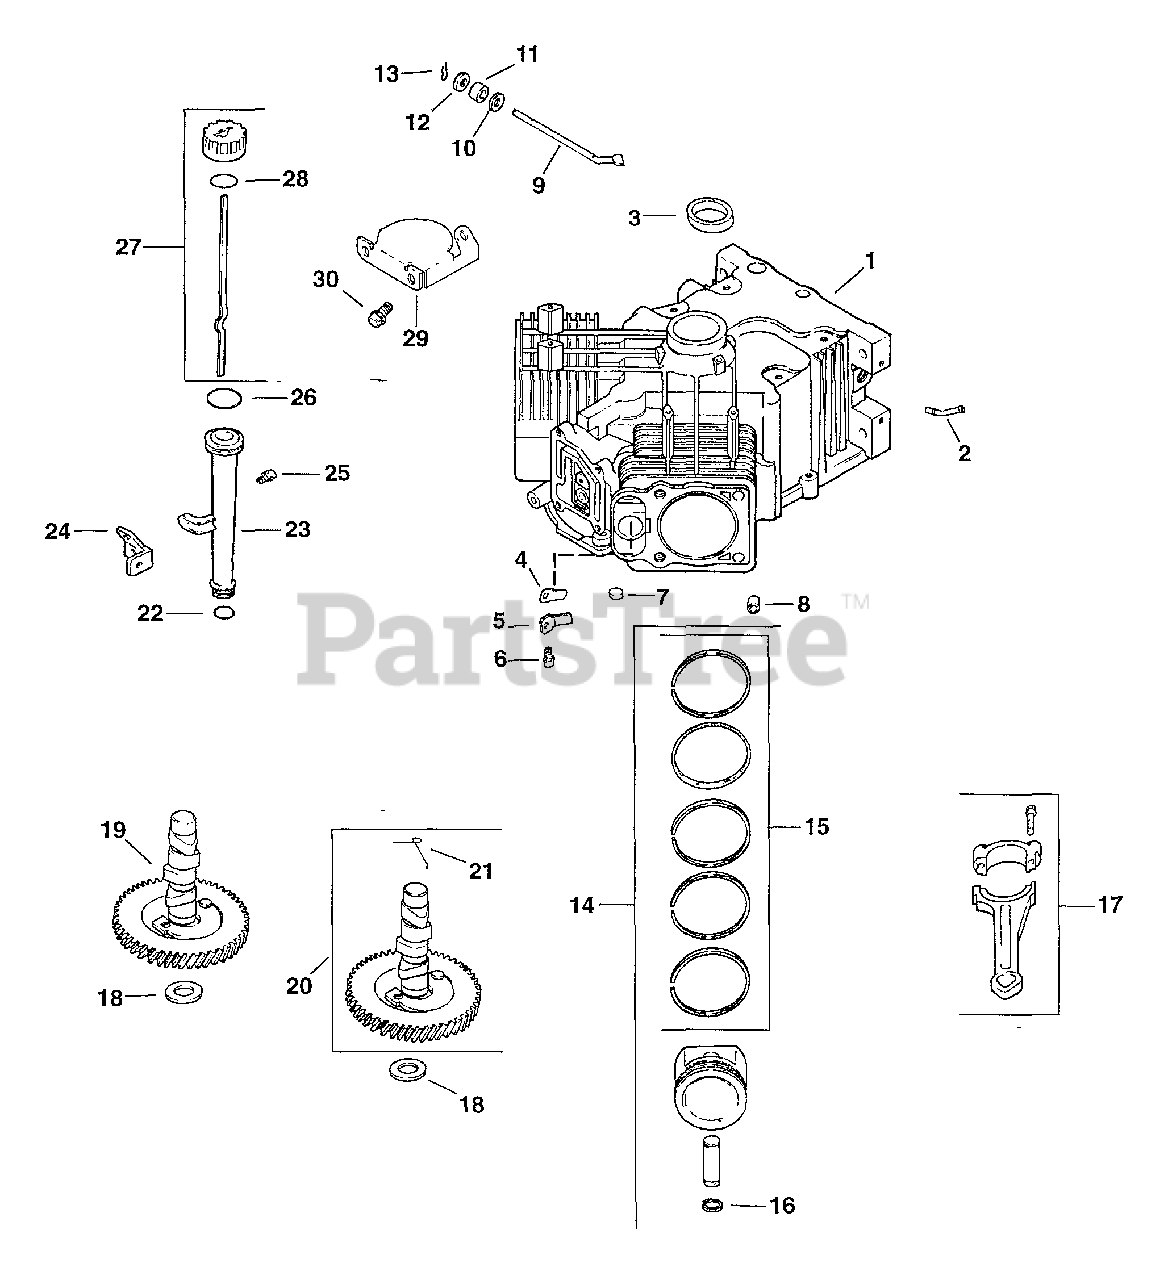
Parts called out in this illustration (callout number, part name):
2	FITTING - USE 24 294 13
3	SEAL, OIL FRONT-USE 24 032 19-S
4	REED, BREATHER
5	RETAINER, BREATHER REED
6	SCREW - USE M-545010
7	PLUG, CUP
8	PIN - USE 12 380 17
9	SHAFT, GOVERNOR CROSS - (#DSC)
10	WASHER, FLAT 1/4"
11	SEAL, GOVERNOR CROSS SHAFT
12	WASHER, FLAT 1/4" (O.D. 1/2")
14	PISTON W/RINGS (STYLE A)(STD) USE 24 874 17-S PISTON
14	PISTON W/RINGS (STYLE A)(.25) USE 24 874 18-S PISTON
14	PISTON W/RINGS (STYLE A)(.50) USE 24 874 19-S PISTON
15	RING SET-USE 24 108 24-S
15	RING SET-USE 24 108 13-S
16	RETAINER, PISTON PIN
17	ROD - USE 24 067 09
17	ROD - USE 24 067 10
18	SHIM, CAMSHAFT (WHITE .028")
18	SHIM, CAMSHAFT (BLUE .03")
18	SHIM, CAMSHAFT (RED .032")
18	SHIM, CAMSHAFT (YELLOW .034")
18	SHIM, CAMSHAFT (GREEN .036")
18	SHIM, CAMSHAFT (GRAY .038")
18	SHIM, CAMSHAFT (BLACK .04")
20	CAMSHAFT - USE 24 010 06
21	SPRING, ACR - DISCONTINUED
22	O-RING, LOWER OIL FILL TUBE
23	TUBE, OIL FILL USE 25 123 07-S
24	BRACKET, OIL FILL TUBE USE 24 126 243-S
25	SCREW - USE M-545016
26	O-RING, UPPER OIL FILL TUBE
27	DIPSTICK, ASSY
28	O-RING - USE 25 153 02-S
